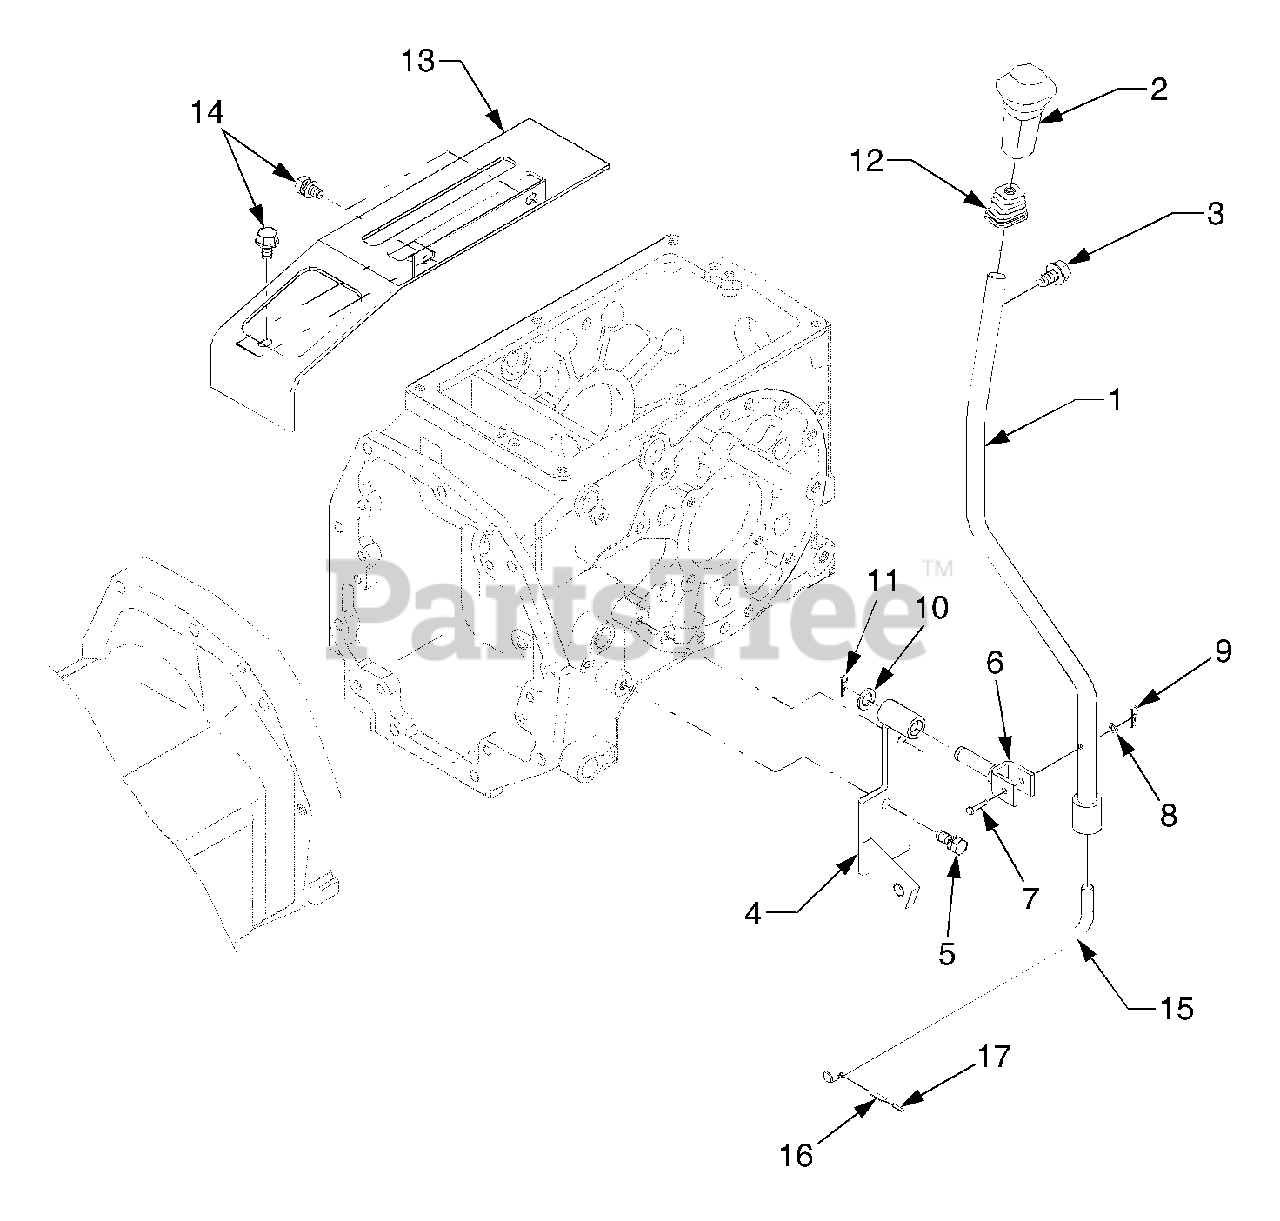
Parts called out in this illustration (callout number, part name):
1	Lever, Main Shift
2	Grip, Main Shift
4	Bracket, Main Shift
6	Pin, Main Shift
8	Washer, Plain
10	Washer, Plain
12	Boot, Main Shift
13	Guide, Shift Lever
15	Rod 1, Main Shift
